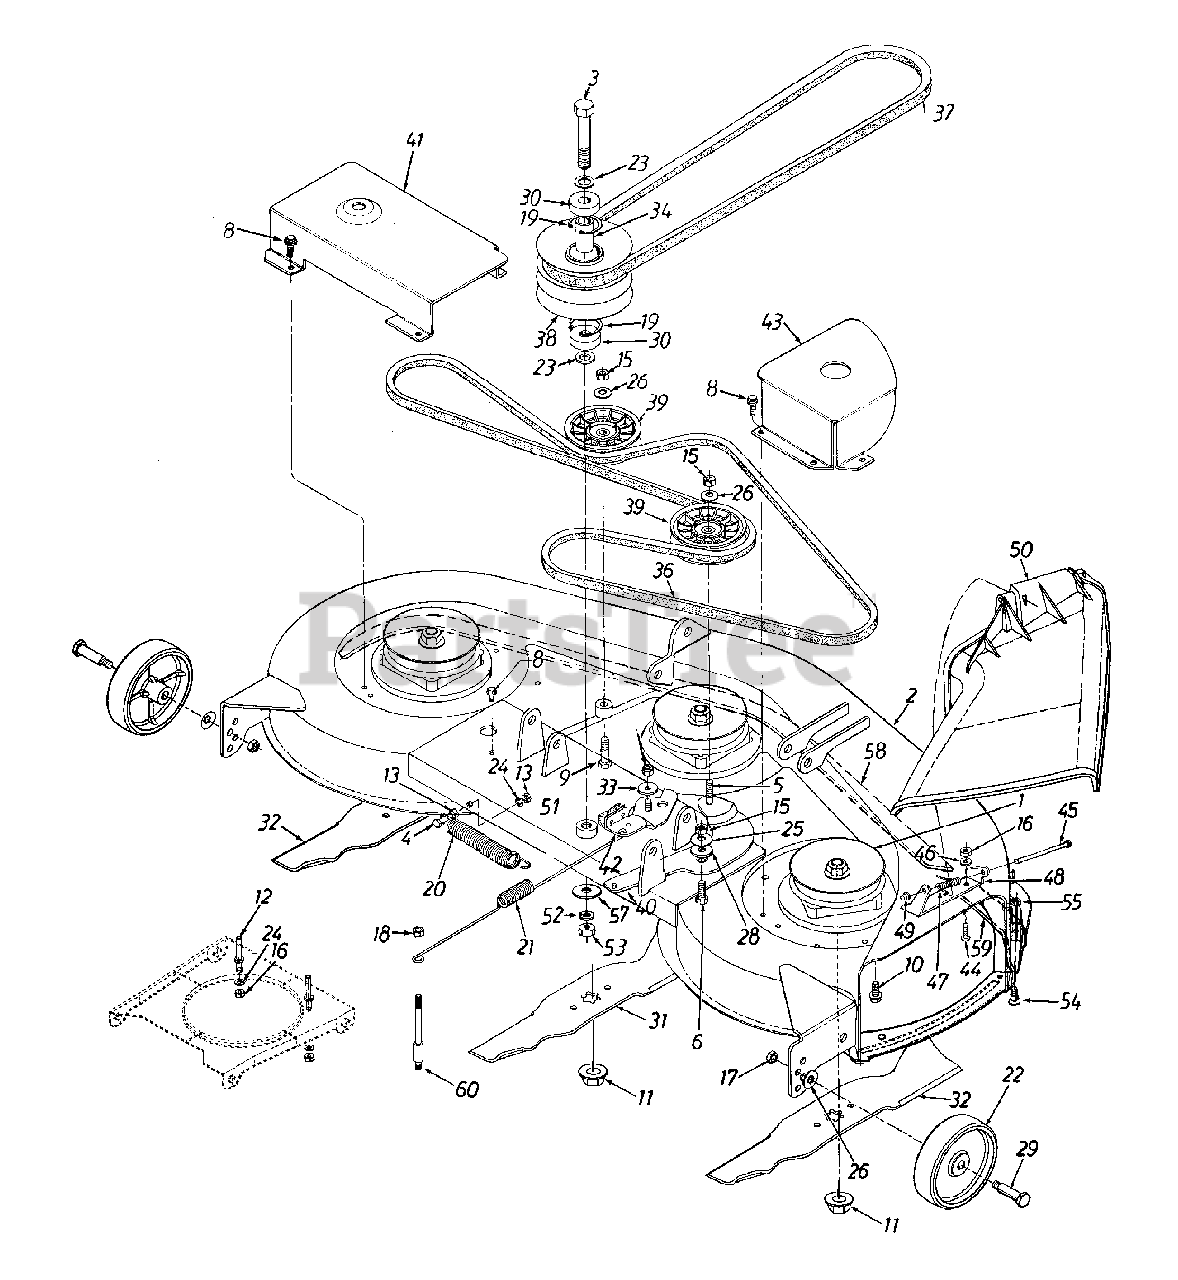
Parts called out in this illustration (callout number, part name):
1	Blade Spindle Ass'y.
4	Hex Bolt 1/4-28 x 1.25" Lg.
5	Hex Bolt 3/8-24 x 1.5" Lg.
6	Hex Bolt 3/8-24 x 1" Lg.
8	Hex Wash. Hd. TT-Tap Scr.
9	Hex Bolt 3/8-24 x 2" Lg.
10	Hex Flange Bolt 5/16-24 x .75"
11	Hex Flange L-Nut 5/8-18 Thd.
12	Belt Guard Pin
13	Hex Nut 1/4-28 Thd.
15	Hex Nut 3/8-24 Thd.
16	Hex Nut 1/4-20 Thd. (Gr. 5)
17	Hex Top Jam Nut 3/8-16 Thd.
18	Hex Center L-Nut 5/16-18 Thd.
19	Int. Snap Ring
20	Ext. Spring .88" O.D. x 6.17"
21	Ext. Spring .788" O.D. x 15.5"
22	Deck Wheel
23	Fl-Wash. .635" I.D. x 1" O.D.
24	L-Wash. 1/4" I.D.
25	Bell-Wash. 3/8" x 1.125" x .062"
26	Bell-Wash. 3/8" x .87" x .064"
28	Shoulder Spacer .625" I.D.
29	Shld. Bolt .498" x 1.525"
30	Ball Brg. .625" I.D. x 1.574" O.D.
31	Blade 14.88" Lg.
32	Blade 16.28" Lg.
33	Shoulder Spacer
34	Spacer .635" I.D. x .088" O.D.
36	V-Belt
37	V-Belt
38	Pulley Double Deck 5" O.D.
39	Flat Idler Pulley 3.5 O.D.
44	Hex Bolt 1/4-20 x .62" Lg.
45	Hinge Pin
46	Bell-Wash. 1/4" I.D.
47	Torsion Spring
48	Hinge Mtg. Brkt.
49	Push Nut
50	Chute Ass'y. Comp.
51	Spacer .635" I.D. x 1" O.D.
52	L-Wash. 5/8" I.D.
53	Hex Nut 5/8-18 Thd.
54	Carriage Bolt 1/4-20 x .5" Lg.
55	Hex Sems Nut 1/4-20 Thd.
57	Fl-Wash. .635" I.D.
60	Return Spring Stud
17258A-0648	Deck Belt Cover, 46" Black - TECH GRAY (0648)
17258A-0665	COVER:BELT:DECK 46 - YARDMAN GREEN (0665)
